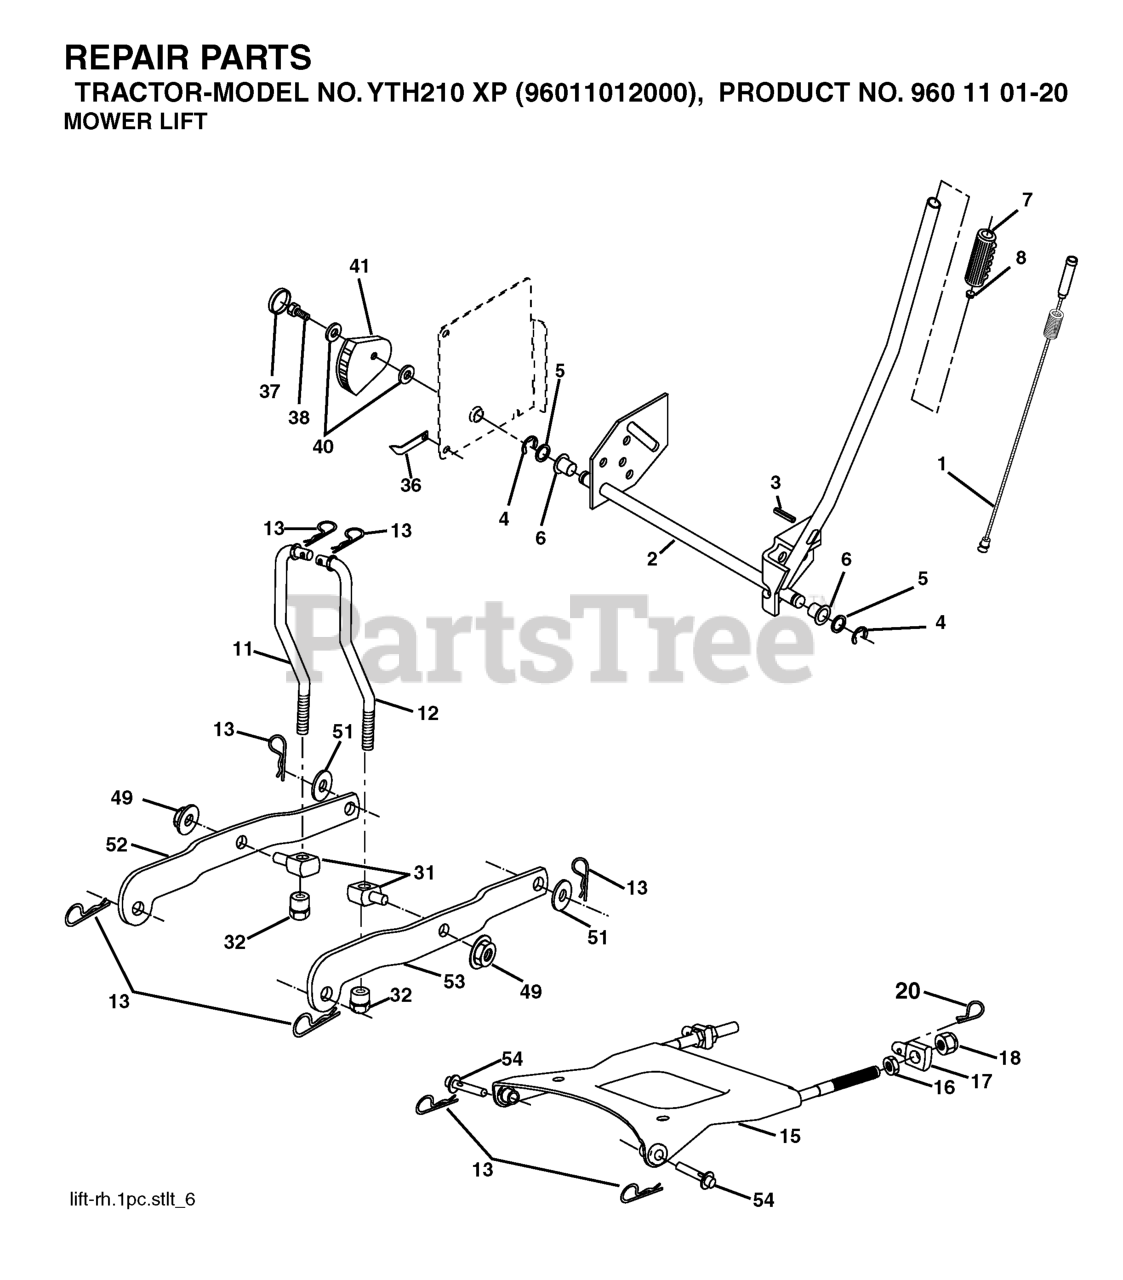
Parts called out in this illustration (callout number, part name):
1	WIRE ASM INNER W/ PLUNGER LT
2	SHAFT ASM R HANDLE
3	PIN GROOVE.
4	RETAINING RING LT
6	BEARING.NYLON
7	GRIP HANDLE
8	PLUNGER BUT KIT
11	LINK LIFT LH
12	LINK LIFT RH
13	RETAINER-SPRNG RB
15	LINK.SUSPENSION.FRONT
16	NUT.HEX.JAM.1/2-13
18	NUT.LK.W/WSH.1/2.
19	ARM.REAR.SUSPENSION
20	PIN.COTTER.7/16.BOW TI.
25	SPRING**
26	RETAINER CLIP
27	ROD ADJ LIFT
28	NUT
29	KNOB INF 3/8-16
31	BEARING.PIVOT.LIFT
32	NUT CROWNLOCK 3/8-24
36	POINTER, HEIGHT INDICATOR(2 2)
38	SCREW 5/16-18X1
41	IND. HEIGHT STLT
49	NUT
50	NUT PUSH M
